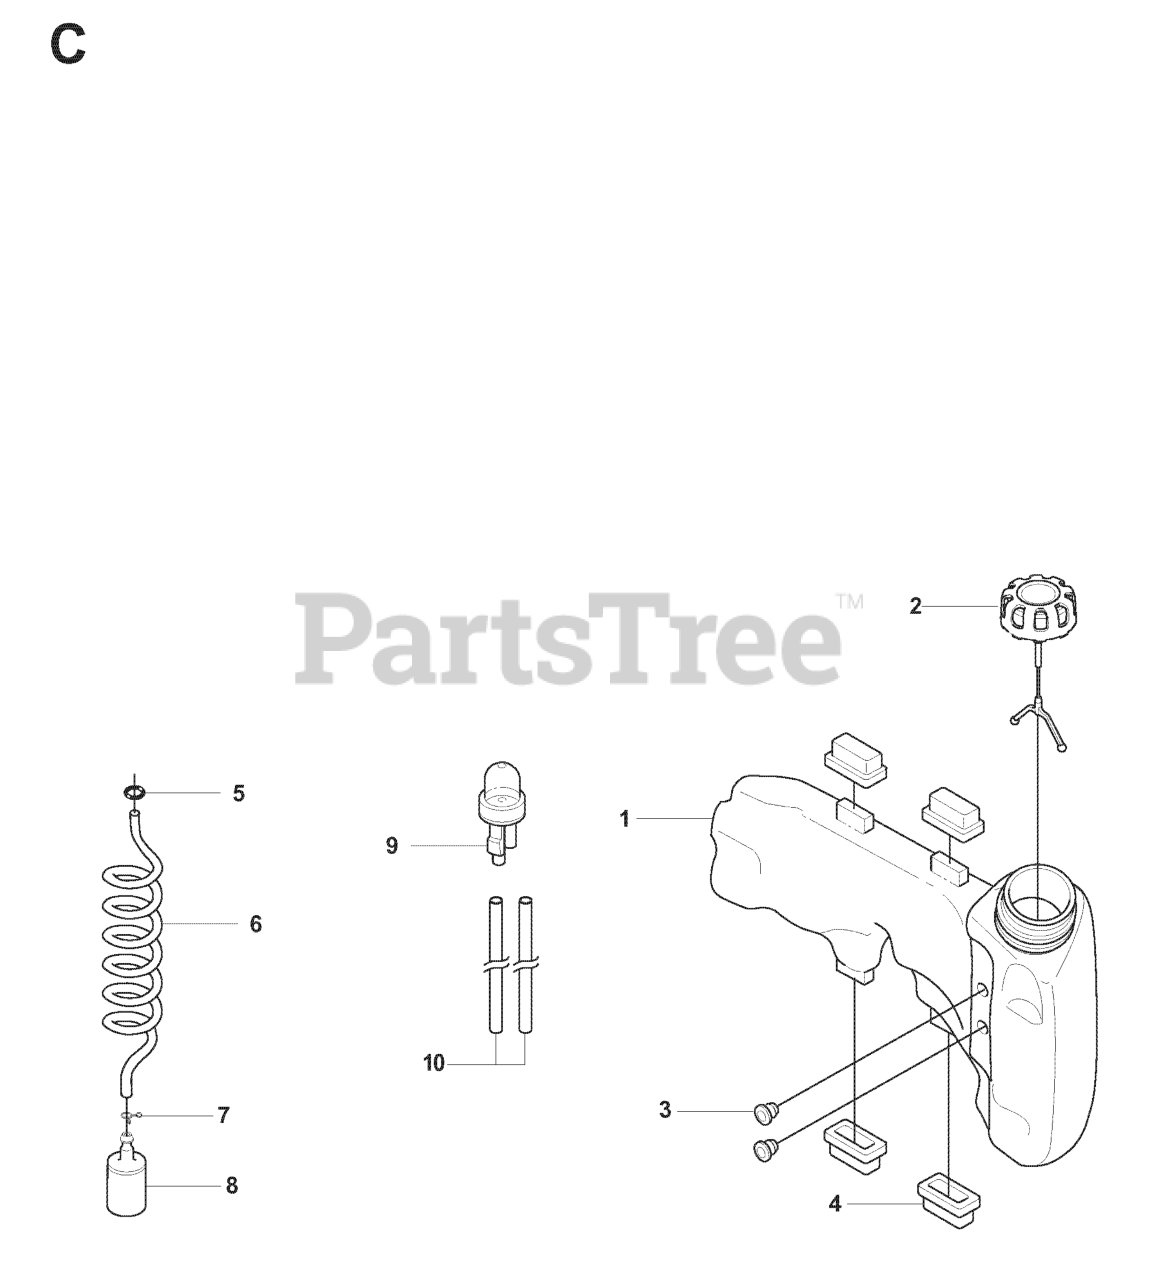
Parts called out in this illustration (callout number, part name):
3	FUEL TANK BUSHING
6	FUEL HOSE
7	HOSE CLAMP
8	RP FUEL FILTER
9	AIR PURGE BUBBLE
10	HOSE
